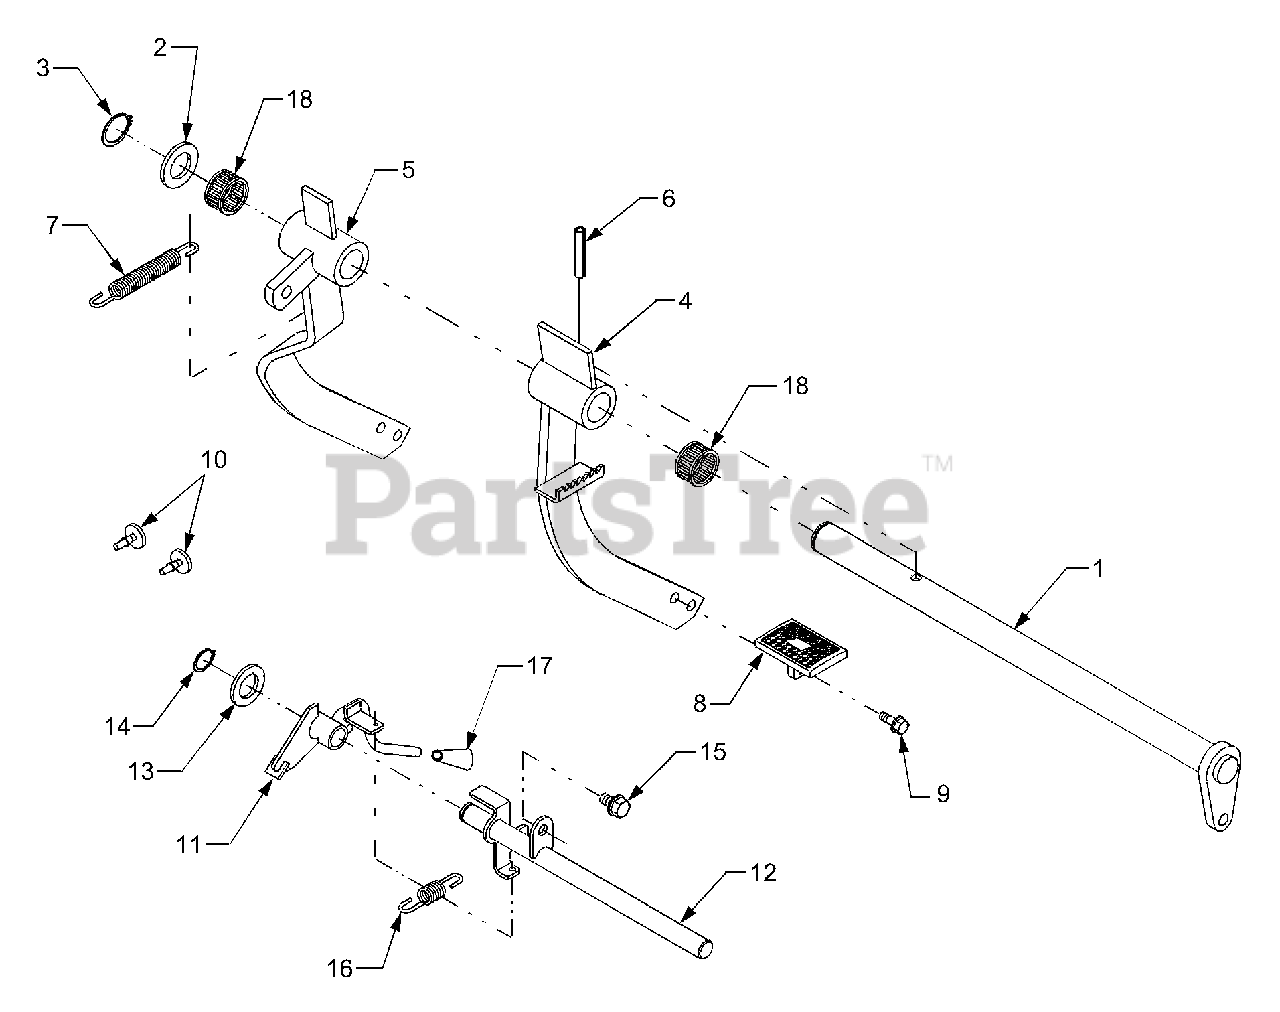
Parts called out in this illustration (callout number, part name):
4	Pedal (LH), Brake
5	Pedal (RH), Brake
7	Spring, Clutch Lock
8	Pedal
10	Cushion, Pedal
11	Brake, Parking
13	Washer, Plain
14	Cir-clip, External
18	Bearing, Needle
